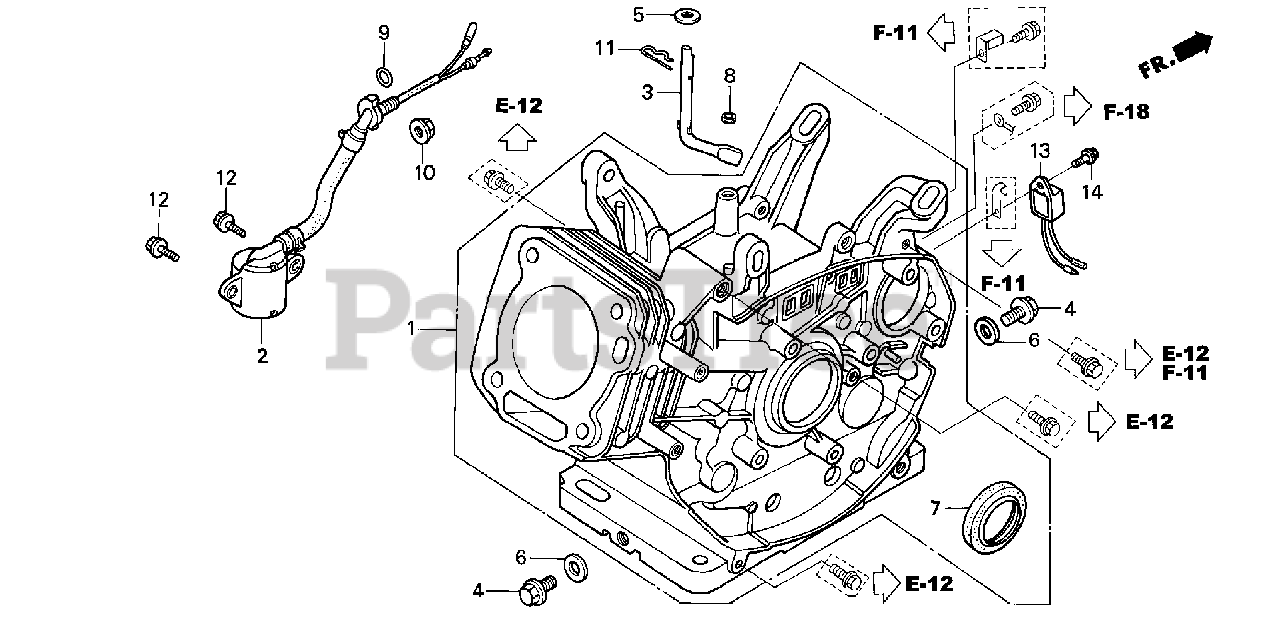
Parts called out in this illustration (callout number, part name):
1	CYLINDER ASSY. (SELF STARTER+ALERT)
2	SWITCH ASSY., OIL LEVEL
3	SHAFT, GOVERNOR ARM
4	BOLT, DRAIN PLUG (12X15)
5	WASHER (8.2X17X0.8)
6	WASHER, DRAIN PLUG (12MM)
7	OIL SEAL (30X46X8)
9	O-RING (14MM) (ARAI)
9	O-RING (14MM) (NOK)
10	NUT, FLANGE (10MM)
11	PIN, LOCK (8MM)
11	PIN, LOCK (10MM)
12	BOLT, FLANGE (6X12)
